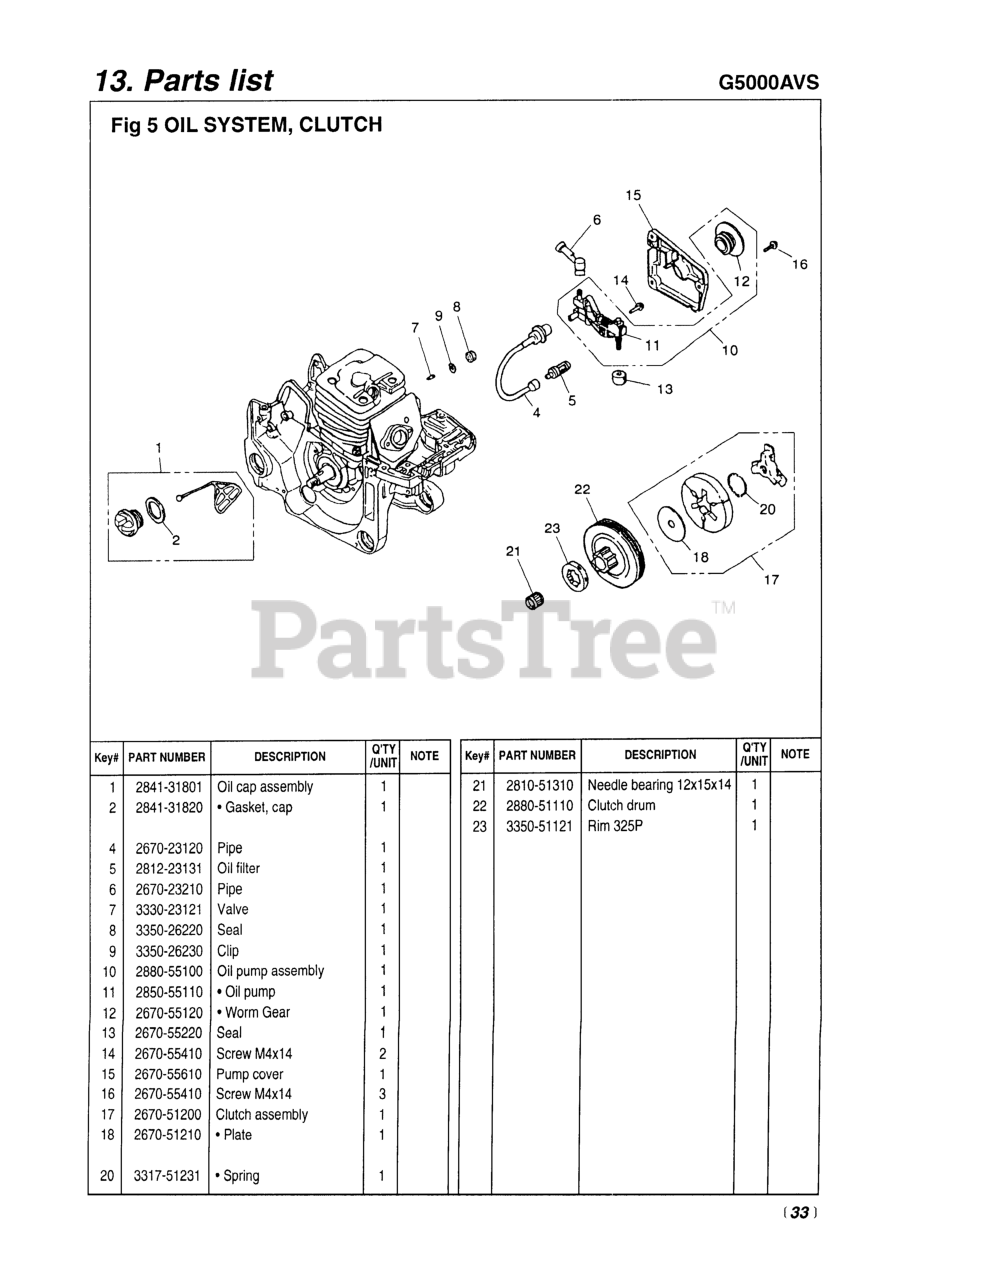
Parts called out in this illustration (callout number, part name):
1	CAP ASSY.
2	GASKET
4	PIPE, OIL
6	PIPE, OIL OUTLET
7	VALVE (RPLS -23120)
8	SEAL, BREATHER
9	CLIP
12	GEAR
13	SEAL
14	SCREW
15	COVER, PUMP
16	SCREW
18	PLATE, THRUST
20	SPRING
21	BEARING (RPLS 2670-51310)
22	DRUM, CLUTCH (RPLS 2670- )
23	RIM SPROCKET, .325, 7-TOOTH
